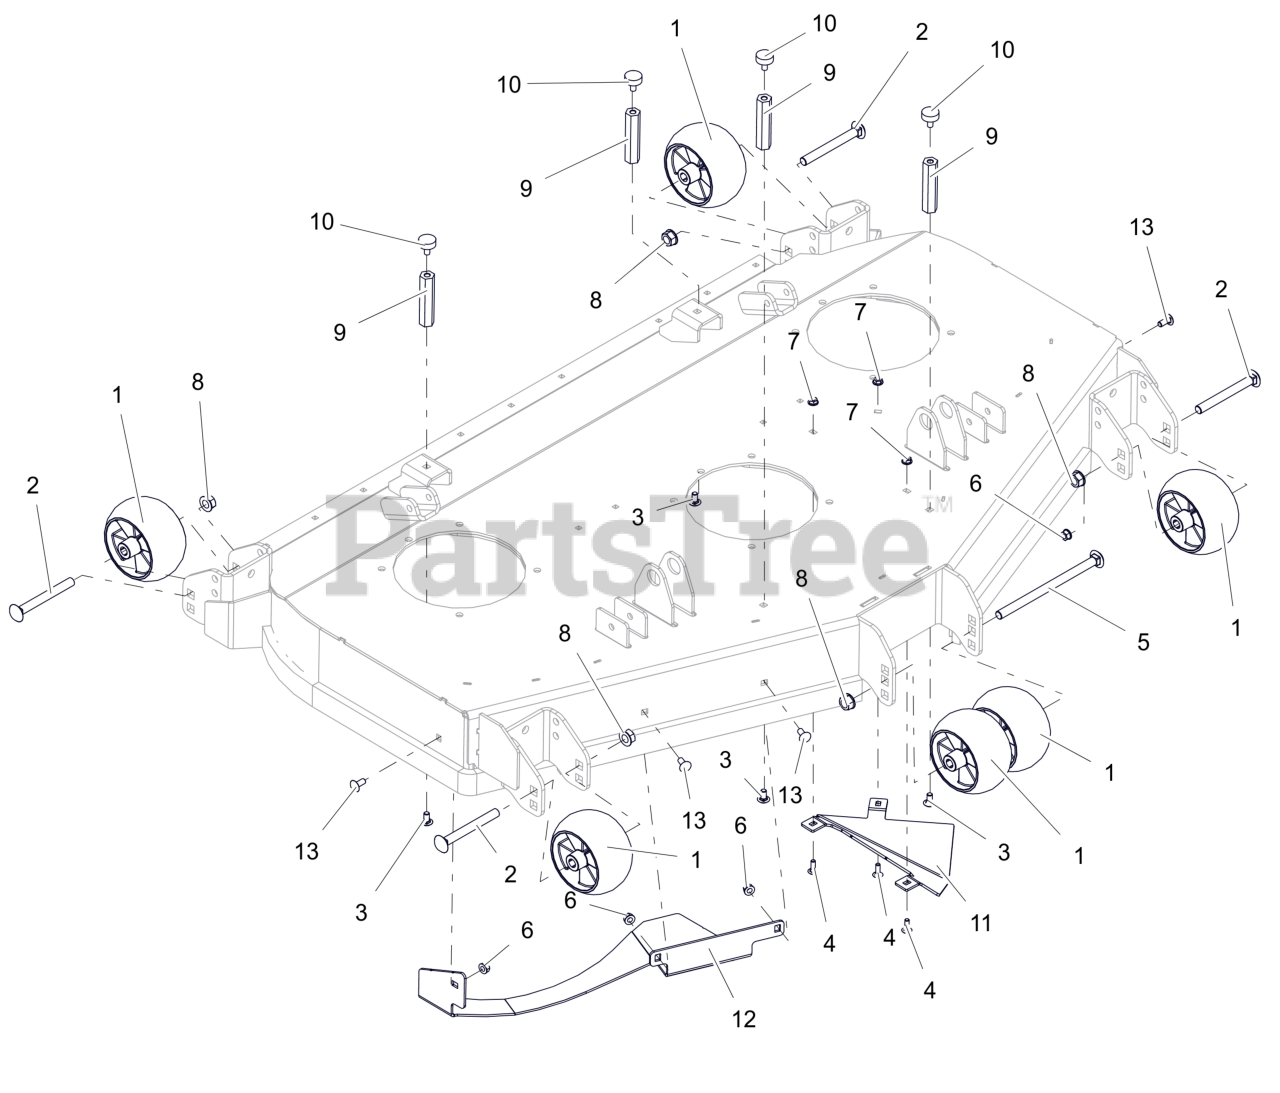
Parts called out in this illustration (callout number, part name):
1	WHEEL, ANTI SCALP - 5X3 CTR W/RIBS
2	BLT,RHSN .50-13X4.50 G5 ZCC
3	BLT,RHSSN.31-18X.625 G5 ZCCP30
4	BLT, RHSN .25-20X.750 G5 ZCC
5	BTL,RHSN .500-13 X 8 G5 ZCC
6	NUT,LK-CTR-FLG .31-18 GF ZCC
7	NUT-LK-CTR-FLG .25-20 ZC120
8	NUT-LK-CTR-FLG .500-13 GG ZCC
9	NUT, COUPLING .312-18 X 3.375
10	BUMPER, RUBBER
11	BAFFLE, 52" TRIANGLULAR INSERT (ORANGE)
12	DEFLECTOR, 52" BOLT-IN BAFFLE (ORANGE)
13	BLT, RHSSN.31-18X.750 G5 ZCC
